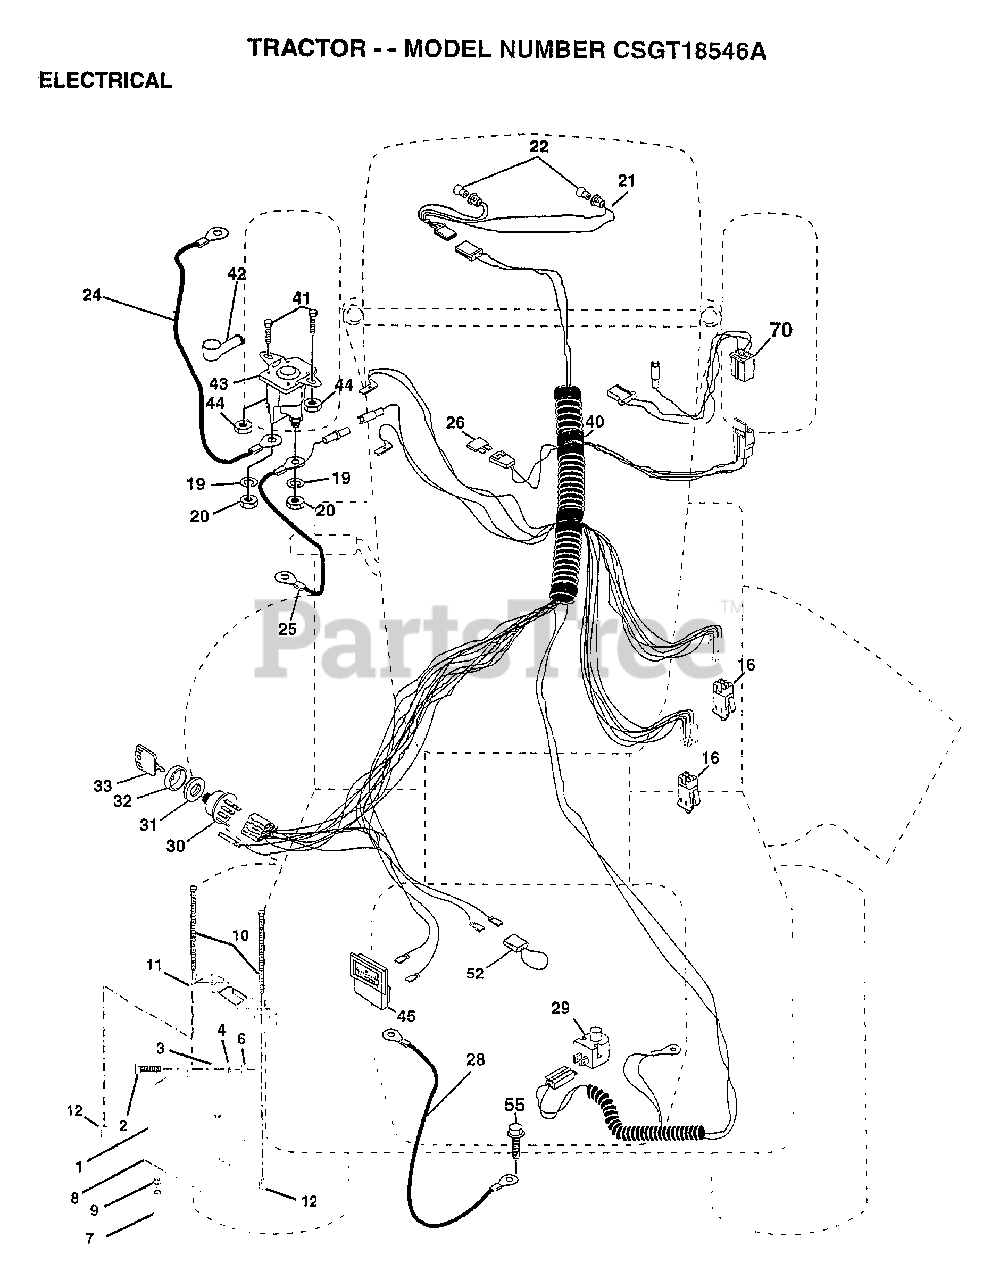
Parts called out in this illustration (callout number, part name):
2	BOLT LT
3	WASHER
4	LOCKWASHER
7	"DRAIN TU T, BATT"
8	"TRAY T, BATTERY"
9	HOSE CLAMP T
11	HOLDDOWN BATTERY
16	SWITCH INTERLOCK
20	NUT
21	"HARNESS,LIGHT SOC"
22	HEADLAMP BULB
24	"CABLE T, BATTERY"
25	CABLE.6GA.22W/16W
26	FUSE HYT
28	CABLE.GRND.6GA.21
29	SWITCH SEAT
30	SWITCH IGN 4POS
31	NUT IGNITION
32	COVER KEY SWITCH
33	KEY
40	HARNESS-IGNITION
41	BOLT HXHD FIN
44	NUT HXKEP 1/4X20
52	PROTECTION LOOP
55	SCREW LT
70	HARNESS ENG DUAL
